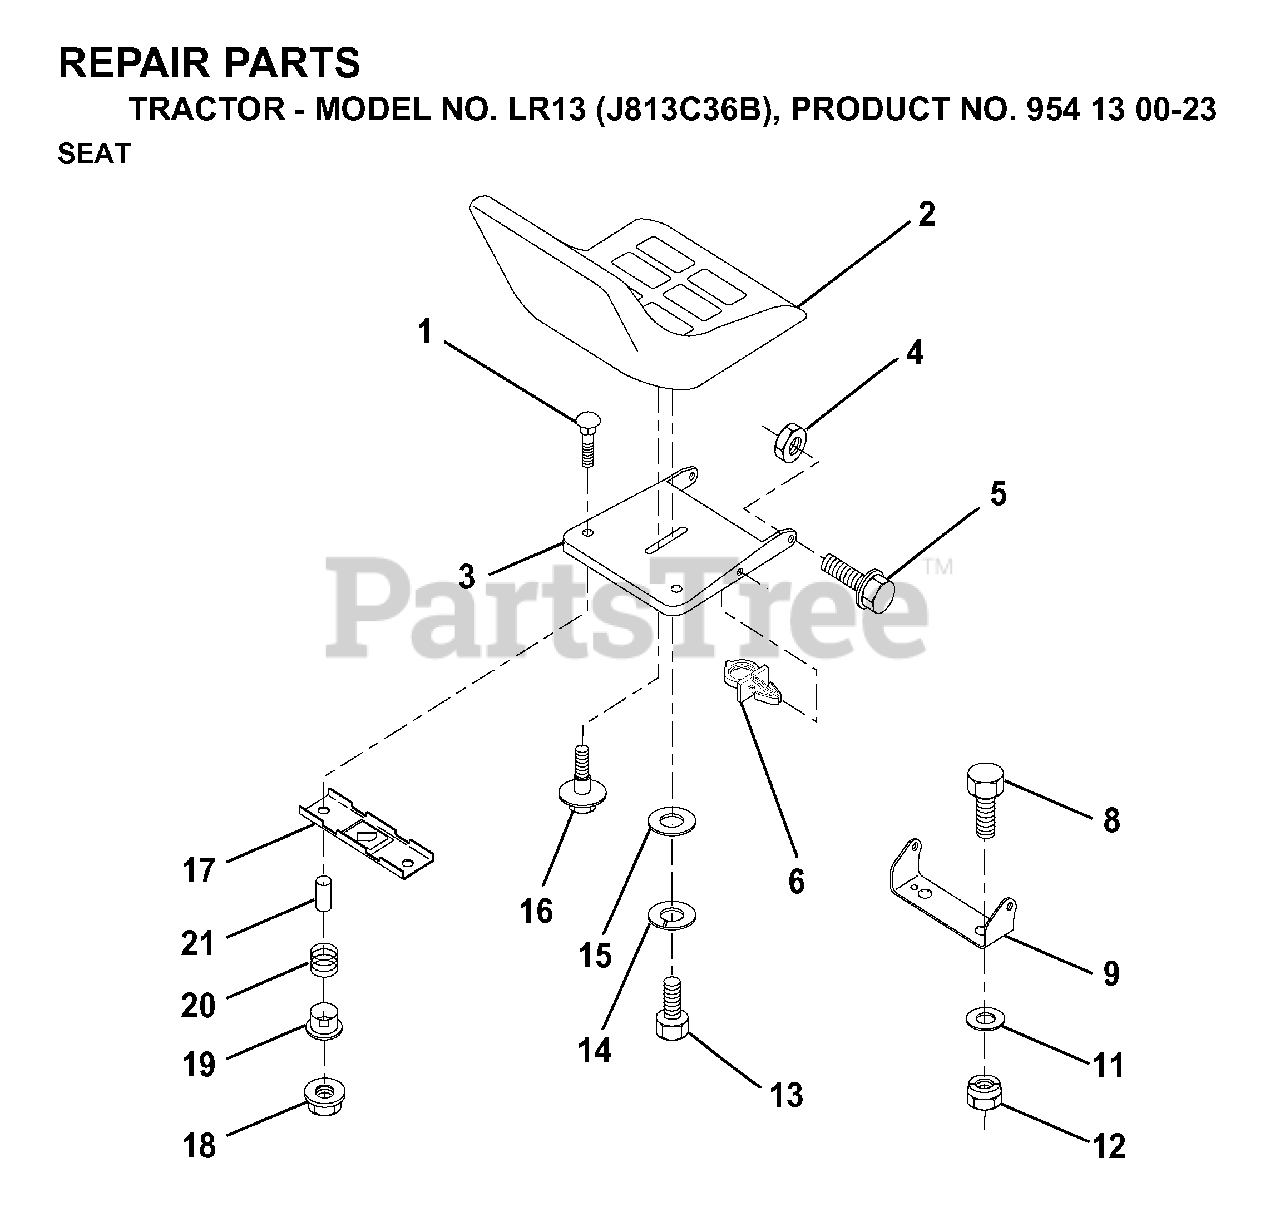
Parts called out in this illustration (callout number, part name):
1	BOLT.ROUND.HEAD.SQUARE.NECK
2	SEAT
3	PAN, SEAT
4	NUT.71038.31-18.HEX.NYLOCK
5	BOLT SHOULDER 5/16-18
6	PUSH CLIP
8	BOLT
9	SEAT PIVOT BRKT
11	WASHER 12/32X2X10GA
12	NUT
13	BOLT
14	LOCKWASHER
16	BOLT,SHOULD
17	BRKT SWITCH
18	NUT T
21	SPACER SPLIT 28X.96
